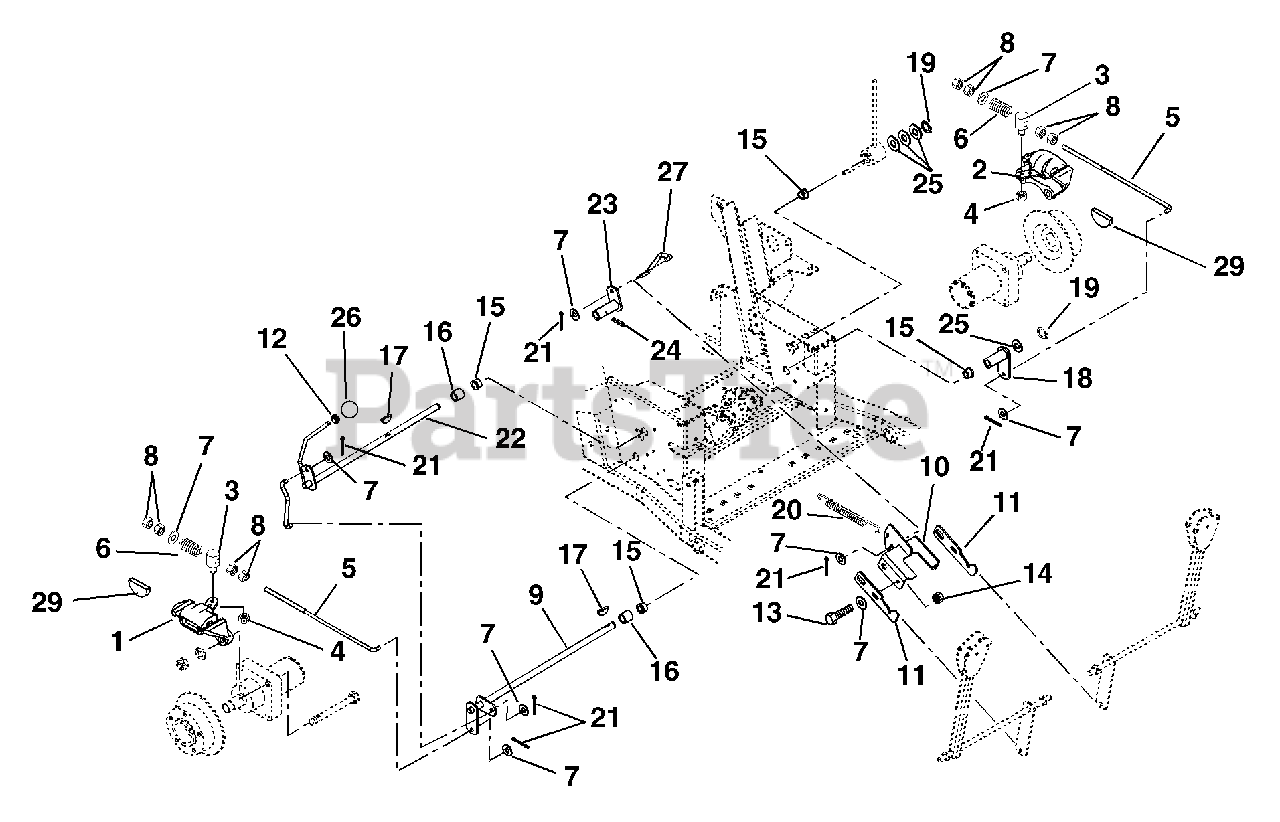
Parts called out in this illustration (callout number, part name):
1	CALIPER PARK BRAKE (CW) RH 2"
2	CALIPER,PARK BRAKE (CCW) LH 2"
3	PIN, PIVOT/TRUNNION
4	@NUT-LK-CTR .31-18 YWZC
5	ROD - BRAKE 12 INCH
6	SG-COMP .142 X .710 X 2.00
7	@WSHR-FL-STL.406X.812X.065 YWZ
8	@NUT-HEX .38-16 YWZC
9	SHAFT - BRAKE CROSS
10	INTERLOCK - FIXED
11	INTERLOCK - ADJUSTABLE
12	NUT-HEX-JAM .375-16 YWZC
13	@BLT-HEX .38-16X1.00 GR5 YWZC
14	@NUT-LK-CTR .38-16 YWZC
15	BSHG-FLG .630X1.000X.625 NY
16	SPACER .630X.878X1.000
17	KEY-WDRF .19X.75 HRD #9
18	ARM - BRAKE LH
19	RG-RTNG-EXT .625X.050
20	SG-TENS .105X.85X5.00 WLD 40
21	@PIN-CTR .09X.75 EXTPRSQCT YWZ
22	SHAFT - BRAKE ACTUATING
23	ACTUATOR
24	PIN-ROLL .125X1.00
25	WSHR-FL-STL .627X.990X.032
26	KNOB-STEERING LOCK
27	ROD - BRAKE ACTUATING
28	@PIN-CTR .09X.75 EXTPRSQCT YWZ
29	PAD SET, DISK BRAKE
